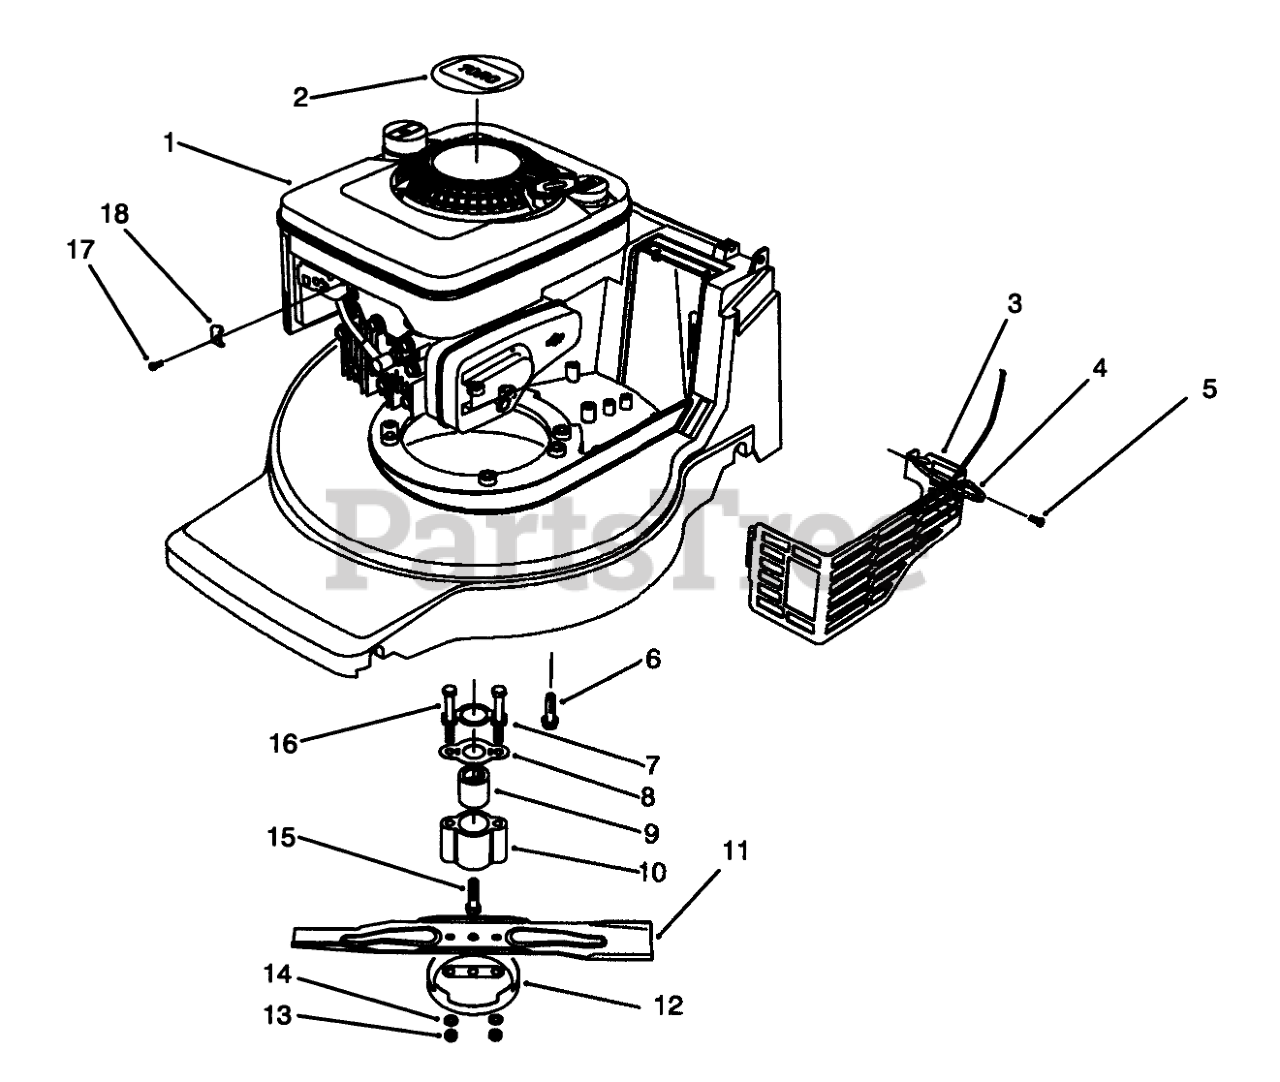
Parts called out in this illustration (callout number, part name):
1	Engine-B&S Quantum
2	DECAL - RECOIL
3	SHIELD-MUFFLER
4	TIE-CABLE
5	SCREW-HWH
6	SCREW-HWH
7	BLADE RETAINER BRKT
8	SPRING FRICTION
10	RETAINER
11	Blade-48cm
12	CUP-SCALP, ANTI
13	NUT-LOCK
14	WASHER
15	SCREW - CRANKSHAFT
16	SCREW - BLADE
17	CLAMP SCREW F/W ENGINE
18	CLAMP-CASING
